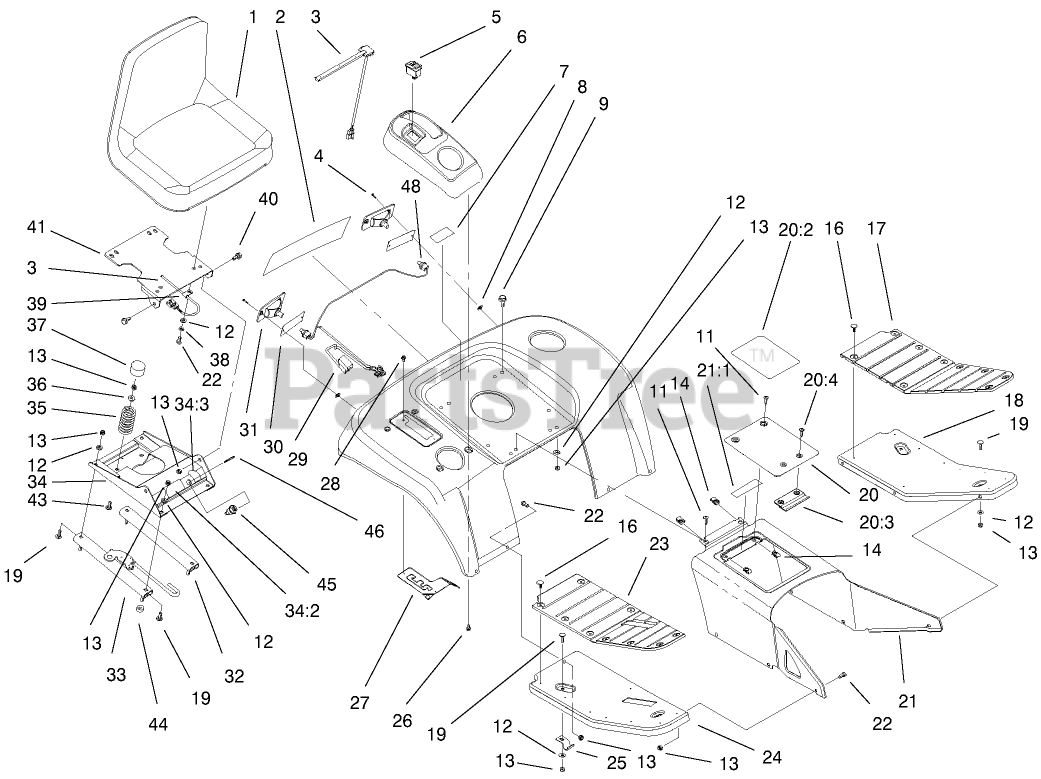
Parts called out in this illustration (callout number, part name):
3	SWITCH-SEAT
4	SCREW-PPH
5	SWITCH-CRUISE
6	POD-CONTROL
6	POD - CONTROL 18 HP
6	POD - CONTROL INT'L
7	DECAL - USA
8	NUT-SPEED
9	SCREW-HHF
11	SCREW-HH
12	WASHER-PLAIN
13	NUT-LOCK, NI
16	FASTENER-PANEL
17	PAD-FOOTREST, LH
18	FOOTREST-LH
19	SCREW-CARR
20	TUNNEL COVER ASM
20:2	DECAL-DANGER
20:2	DECAL - DANGER
20:3	RETAINER-COVER
20:4	SCREW-PPH
21	TUNNEL ASM
21:1	DECAL - WARNING
21:1	DECAL-DANGER
22	SCREW-HH
24	FOOTREST-RH
25	BRACKET-FOOTREST
26	SCREW-HWH
27	GATE-HI / LO SHIFT
28	SCREW-HWH
29	HARNESS-REAR
31	REFLECTOR
31	LAMP-TAILLIGHT
32	SLIDE-SLAVE, SEAT
33	SLIDE-LATCH, SEAT
34	SEAT BASE ASM
34:2	DECAL-DANGER
34:3	DECAL-SWITCH, NMIR
35	SPRING-COMPRESSION
36	BUSHING
37	CAP-SPRING, SEAT
38	WASHER-LOCK
39	CLAMP-R
40	BOLT-SHOULDER,HFH
43	SCREW-CARR
44	WASHER-FLAT
45	STARTER SWITCH ASM
46	KEY-IGNITION
48	LIGHT BULB
